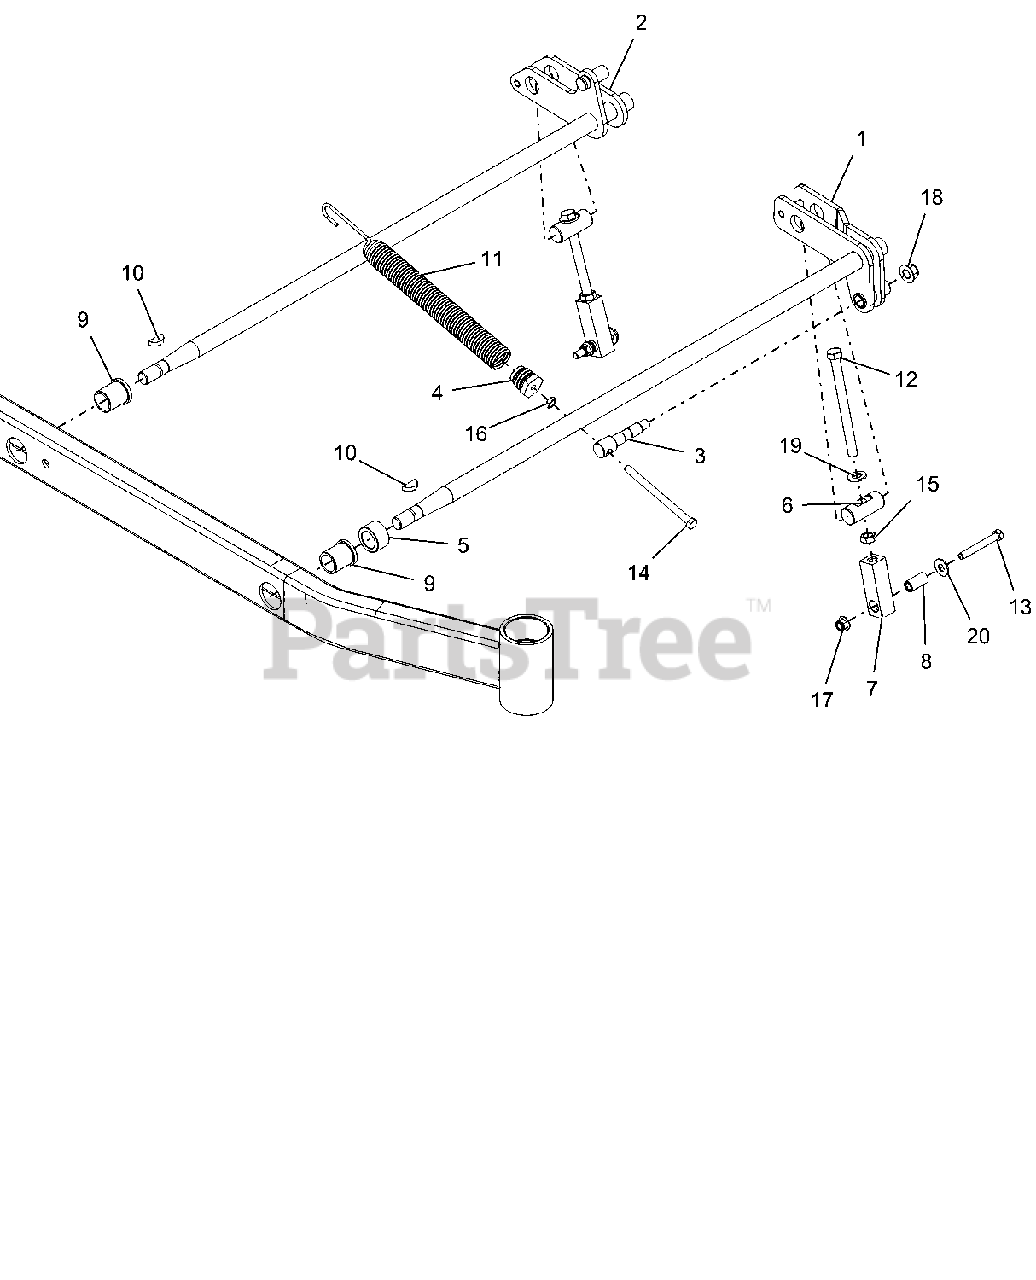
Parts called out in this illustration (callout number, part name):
1	WLDMT, FRONT LH DECK LIFT ARM (BLACK)
2	WLDMT, REAR LH DECK LIFT ARM (BLACK)
3	TRUNION, SPRG
4	PLUG, SPRG
5	SPACER, 1.500 X 1.000 X .880
6	PIN, DECK LIFT
7	LINK, DECK LEVELING
8	SPCR, DECK LEVELING
9	BSHG-FLG 1.00X1.25X1.5X1.5
10	KEY, WDRF .25 X 1.00 HRD #15
11	SPRG, DECK LIFT
12	BLT-HEX .50-13X6.00 2.5 THD GR5 YWZC
13	BLT-HEX .38-16X2.75 GR8 YWZC
14	BLT-HEX .38-16X5.00 GR5 YWZC
15	NUT, JAM .500-13 YWZC
16	NUT, JAM .375-16 YWZC
17	NUT-LK-NYL-FLG .38-16 YWZC
18	NUT-LK-NYL-FLG .50-13 YWZC
19	WSHR-FL-STL .557X1.040X.102 YWZC HARD
20	WSHR-FL-STL.438X1.00X.083 YWZC
